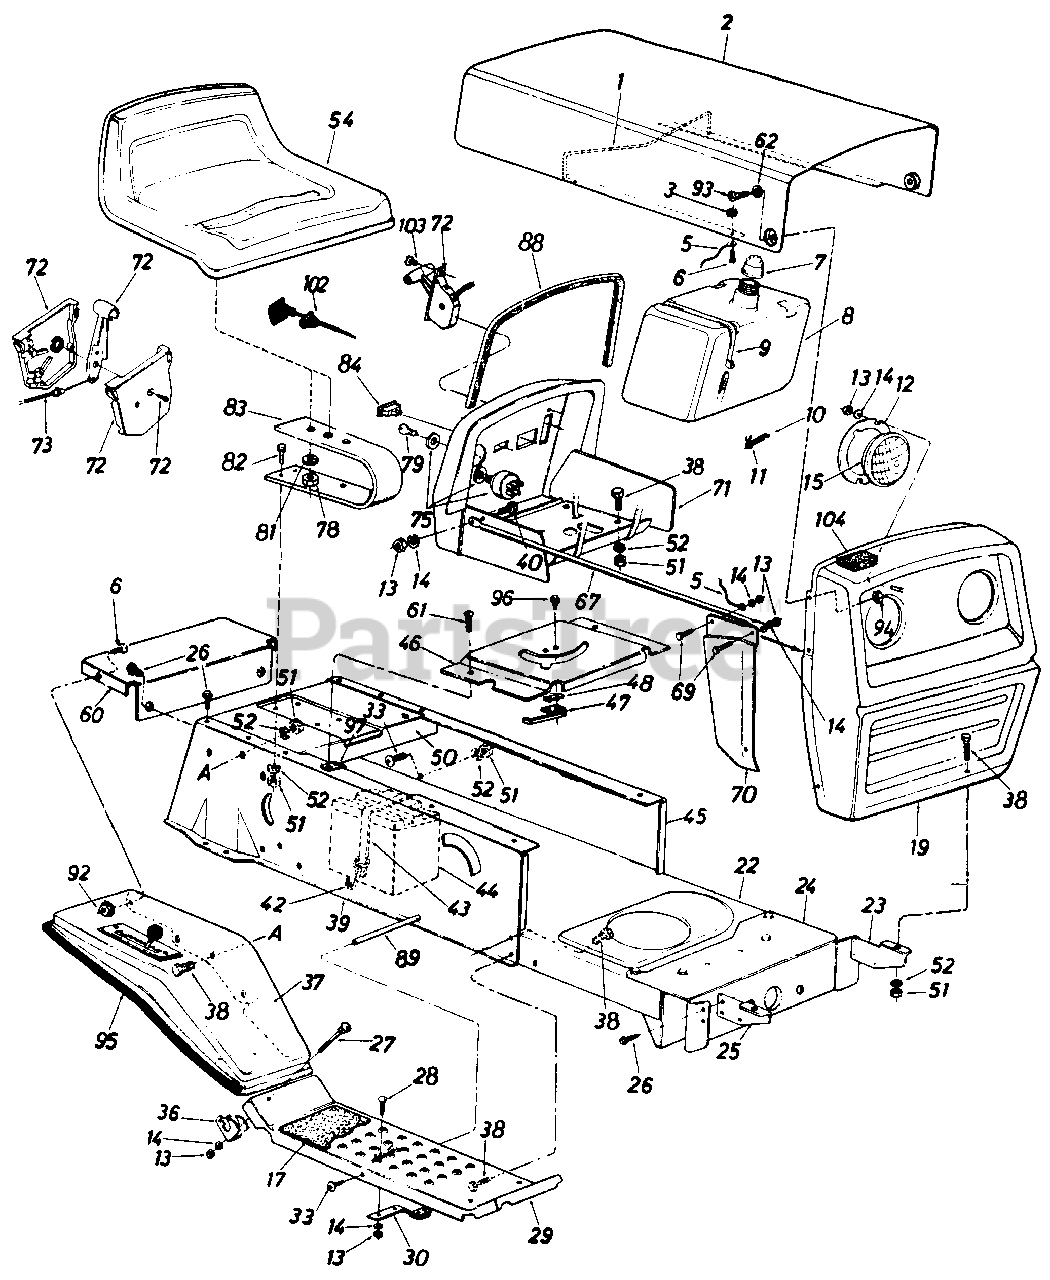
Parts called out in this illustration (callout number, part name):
1	Hood Spring
2	Hood
3	Hex Sems Nut #10-24 Thd.
5	Hood Stop 7" Lg.
6	Truss Hd. Scr. #10-24 x 1/2"
7	Fuel Cap Gauge
8	Fuel Tank
9	Tie Strap
10	Fuel Line
11	Hose Clamp
12	Headlight Retainer
13	Hex Nut 1/4-20 Thd.
14	L-Wash. 1/4" I.D.
15	Headlight
17	Foot Pad
23	Grille Mount Brkt. L.H.
24	Front Pivot Brkt.
25	Grille Mount Brkt. R.H.
26	Hex Wash. Hd. AB-Tap Scr. 5/16 x .75" Lg.
27	Carriage Bolt 1/4-20 x 2.0
28	Carriage Bolt 1/4-20 x .62"
29	Running Board
30	Blade Brake Ass'y.
33	Truss Mach. Scr. 5/16-18 x .75" Lg.
36	Fender Clamp
37	Fender
39	R.H. Side Frame
40	Hex Bolt 1/4-20 x .62" Lg.
42	Battery Strap Hook
43	Battery Hold Down Strap
44	12-V Battery
45	L.H. Side Frame
46	Shift Cover
47	Reverse Safety Switch
48	Insulator Nut Plate
50	Hitch Plate
51	Hex Nut 5/16-18 Thd.
52	L-Wash. 5/16" I.D.
54	Seat Ass'y.
62	Washer .39" I.D. x .62"
67	Grille Support Rod
69	Truss Hd. Scr. 1/4-20 x .75"
70	R.H. Grille Side Panel
73	Throttle Control Wire
75	Ignition Switch
78	Hex Nut 1/2-13 Thd.
79	Ignition Key
81	L-Wash. 1/2" I.D.
82	Hex Bolt 5/16-18 x 1.0"
83	Seat Spring 5.5" High
84	Light Switch
88	Molding Strip 27" Lg.
89	Running Board Rod
92	Hex Sems Nut #10-24 Thd.
93	Shld. Bolt .375" I.D. x .125
94	L-Nut 1/4-28 Thd.
95	Trim Strip 57" Lg.
96	Hex Wash. Hd. AB-Tap Scr. #8 x .50" Lg.
97	Speed Nut #10Z
102	Choke Control 29" Lg.
103	Truss Mach. AB-Tap Scr. #10 x .50" Lg.
104	Foam Strip 3/8 x 1-1/8 X 1-1/2
